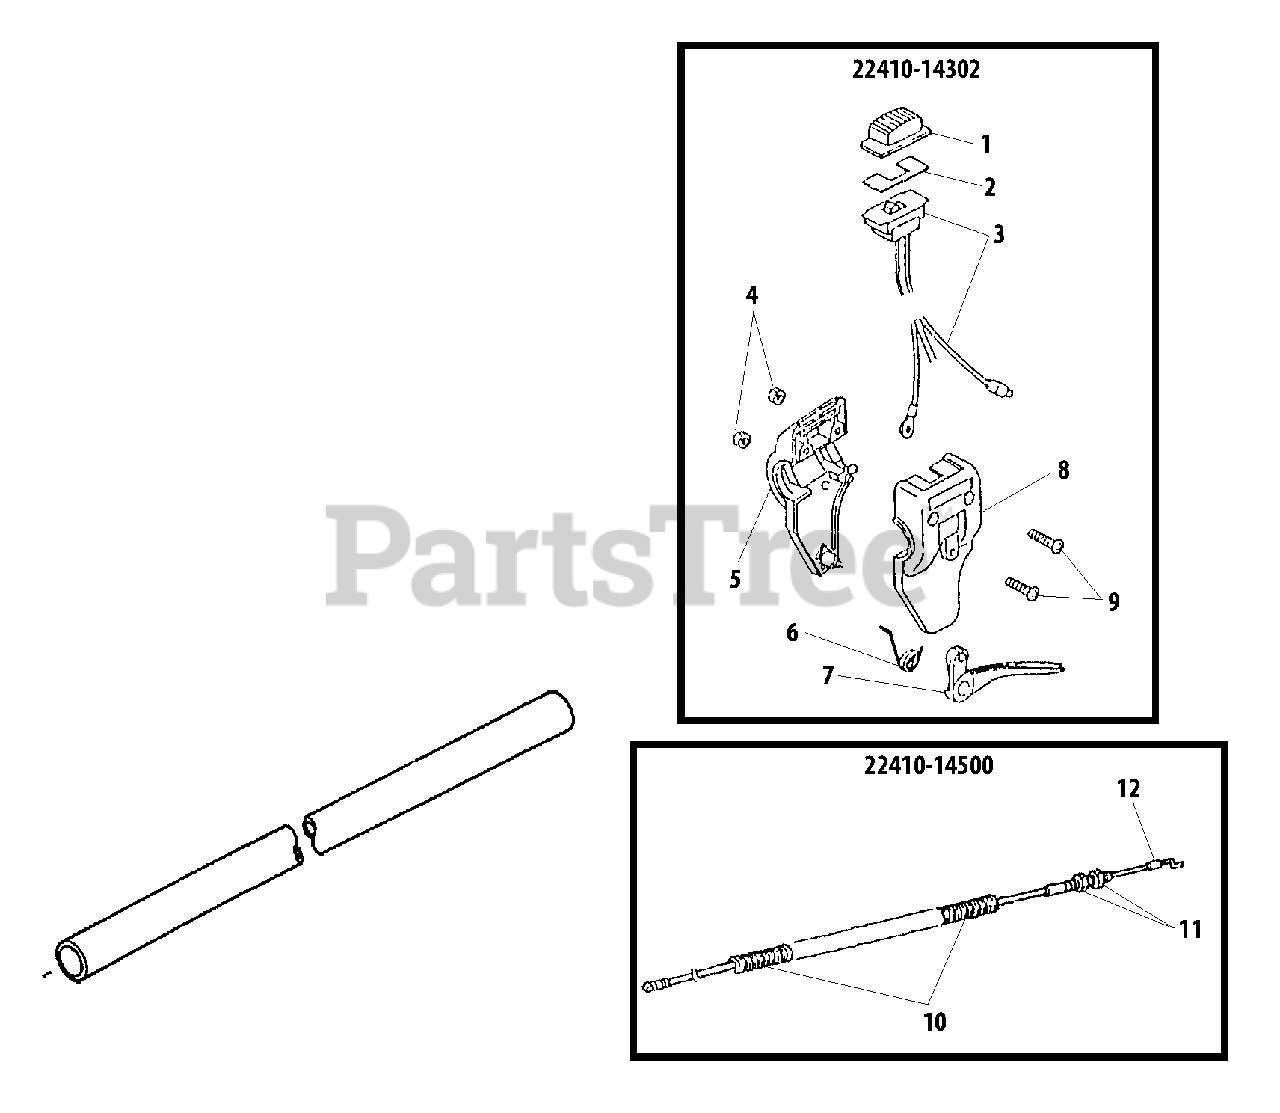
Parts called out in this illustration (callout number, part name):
1	KNOB, SWITCH
2	PLATE, SWITCH
3	SWITCH
4	NUT M5
5	CONTROL HANDLE - RIGHT
6	SPRING, RETURN
7	TRIGGER, THROTTLE
8	CONTROL HANDLE - LEFT
9	SCREW
10	TUBE, PLASTIC PROTECTIVE
11	NUT M6
12	CABLE, THROTTLE
22410-14302	THROTTLE CONTROL KIT
22410-14500	THROTTLE CABLE ASSY
